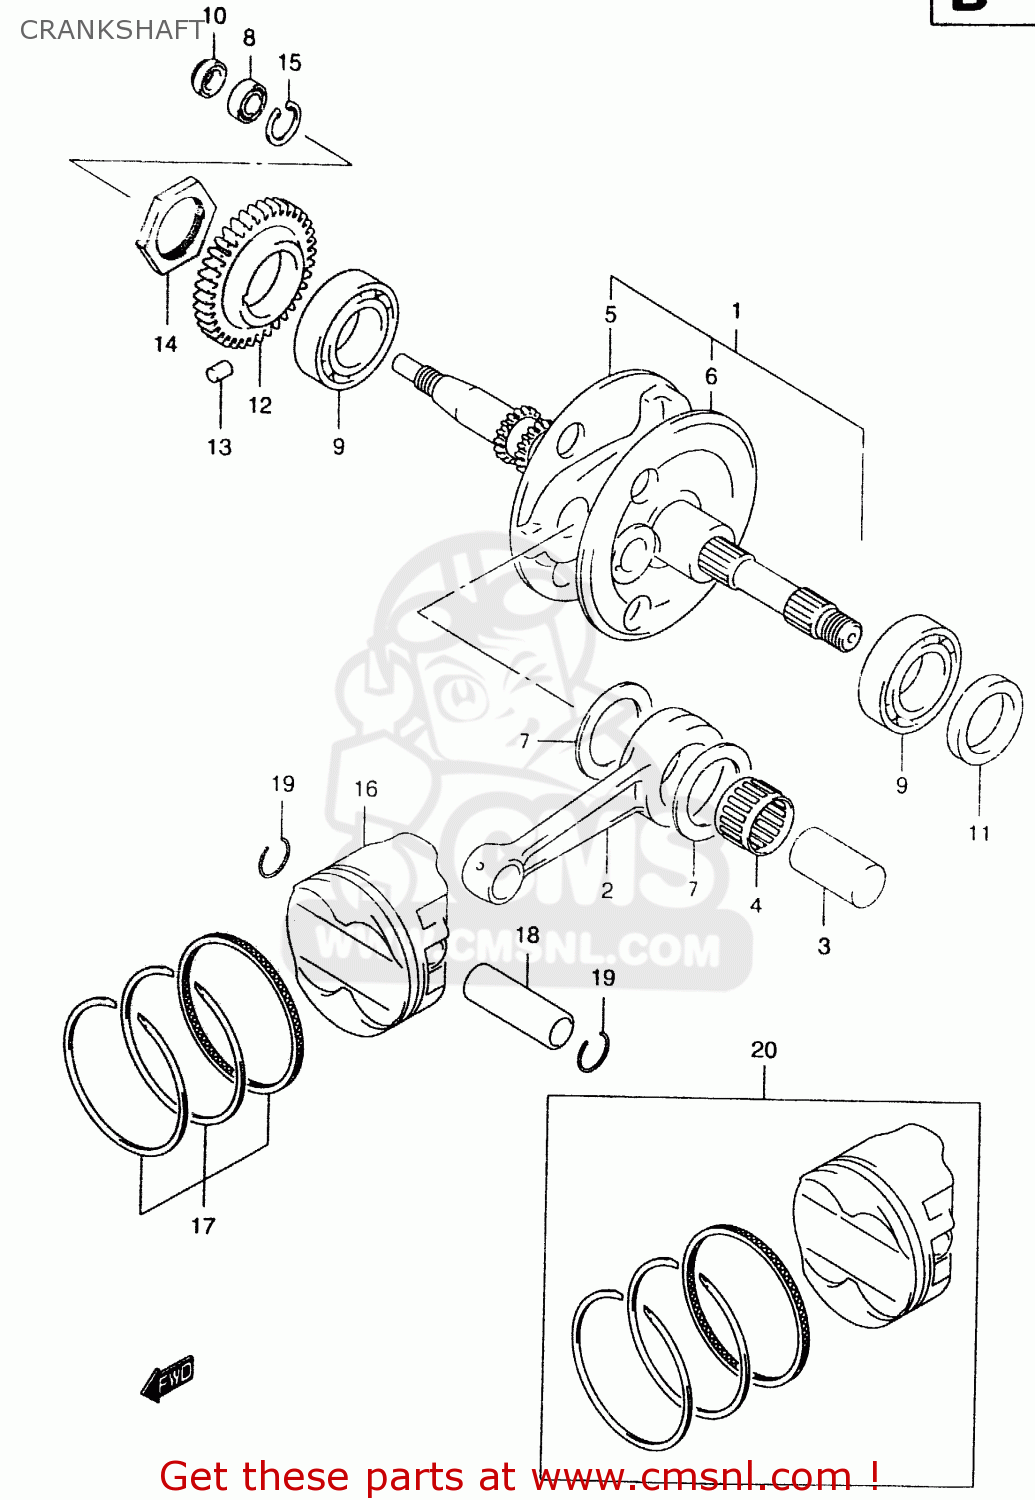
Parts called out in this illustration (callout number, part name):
1	CRANKSHAFT ASSY
2	CONNECTING ROD
3	PIN COMP,CRANK
4	BEARING(34X43X22)
5	CRANKSHAFT,R
6	CRANKSHAFT, LH
7	WASHER(34X52X1)
8	BEARING(12X32X10)
9	BEARING 35X72X17
10	SEAL,OIL(12X29X6)
11	SEAL,OIL(34X52X6)
12	GEAR,CRANK BALANCER DRIVE
13	PIN(5X8)
14	NUT,FLYWHEEL
15	CIRCLIP
16	PISTON (73.00MM)
17	RING SET,PISTON
18	PIN,PISTON
19	RING,SNAP
20	PISTON SET(OS:0.5)
